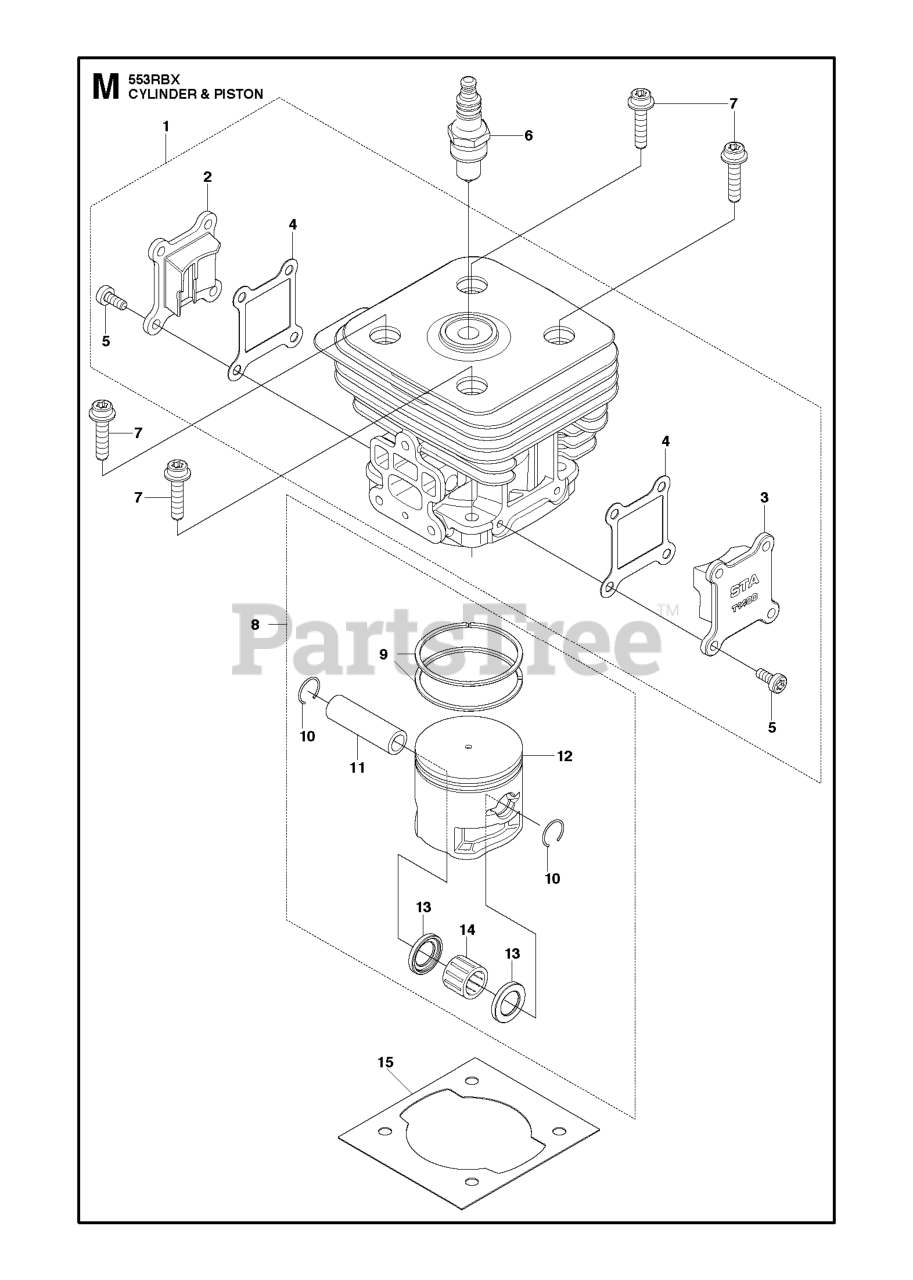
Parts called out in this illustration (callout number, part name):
4	GASKET, TR
5	SCREW
6	PLUG CMR7H
7	BOLT TORX
10	RING, SNAP
11	PIN, PISTON
13	WASHER, THRUST
14	BEARING (RPLS 335041410)
